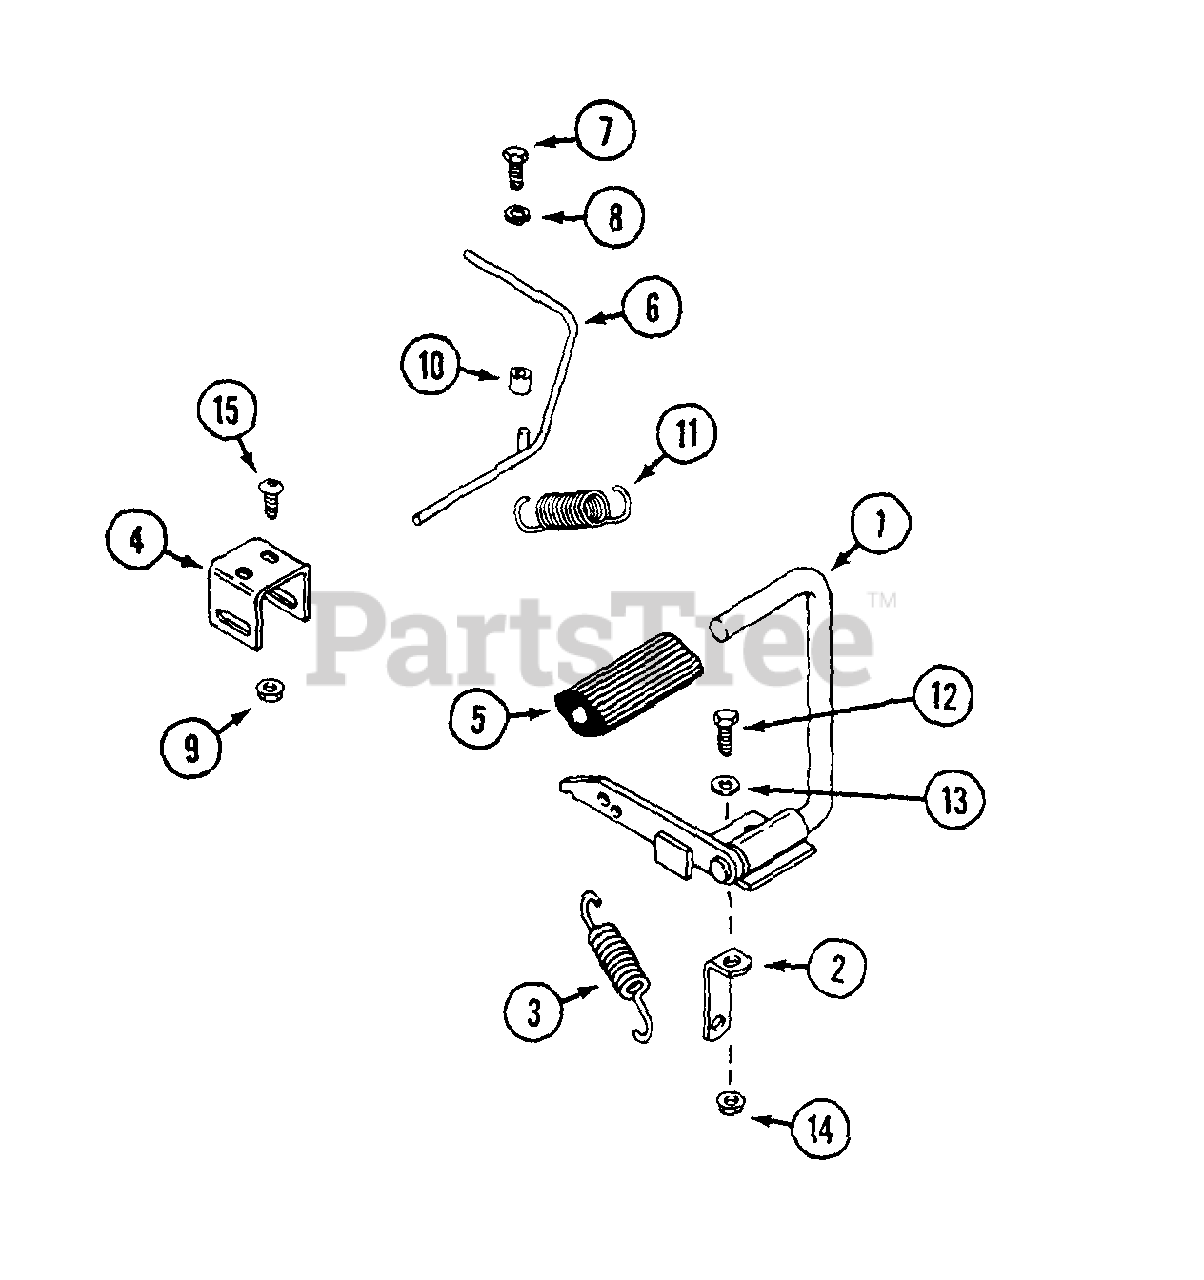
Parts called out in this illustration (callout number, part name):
1	PEDAL - parking brake
2	TAB - spring mount
3	SPRING - brake return
4	BRACKET - brake lock
5	PAD - brake pedal
6	LEVER - brake lock
7	SCREW - 5/16" - 18 x 5/8" allen head
8	LOCKWASHER - 5/16"
9	NUT - 1/4" - 20 flange lock
10	TAB - pivot
11	SPRING - return, lock lever
12	BOLT - 5/16" - 18 x 1"
13	WASHER - 5/16"
14	NUT - 5/16" - 18 flange lock
15	SCREW - 1/4" - 20 x 1/2" allen head
